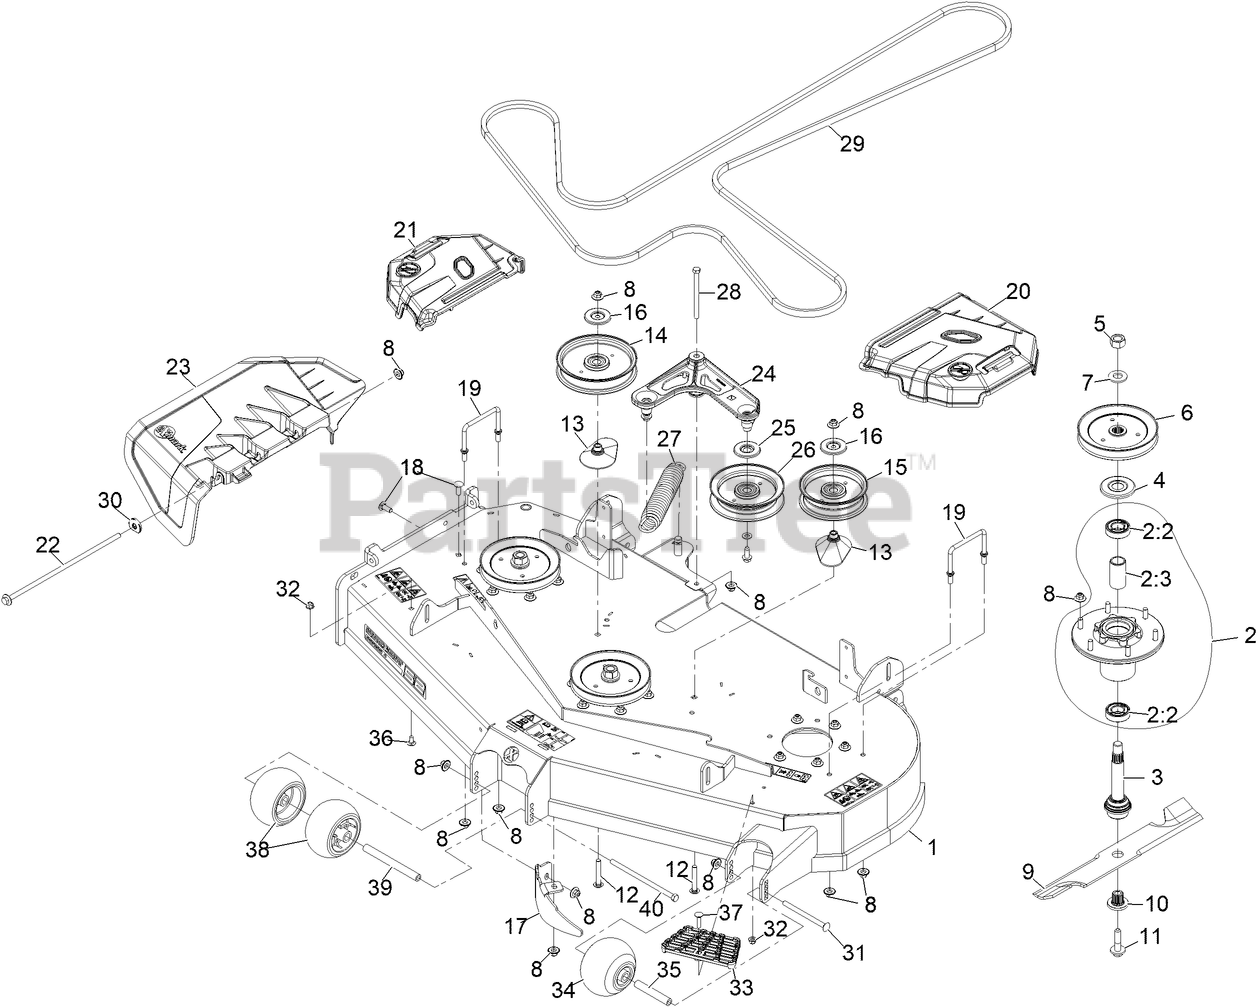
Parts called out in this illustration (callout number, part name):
1	ASM-Deck W/Decals 524
2	ASM-CUTTER HSG WITH BEARINGS
2:2	BEARING-BALL
2:3	SPACER-BEARING
3	ASM-SPINDLE AND SEAL
4	GUARD-BEARING, TOP
5	NUT-HEX
6	SHEAVE,BLADE DRIVE 6.50
8	Nut-Nyloc 3/8-16 Flg
10	BUSHING,SPLINED
11	SCREW,SEMS 1/2-20 X 2.19
12	SCREW-CARR
13	SPACER-PULLEY
14	IDLER-PULLEY, FLAT 6.00X1.00
15	IDLER-PULLEY, FLAT 5.00X1.31
16	SHIELD-DUST
17	BAFFLE-DOGLEG, LZ-VT52
18	SCREW-CARR
19	WIREFORM-COVER
20	SHIELD, LT
21	SHIELD, RT
22	Pin, Chute
23	Chute-Deck Discharge
24	ASM-IDLER ARM W/BEARINGS
25	SHIELD-GUARD, DUST
26	IDLER-PULLEY, FLAT
27	SPRING-EXTENSION
28	SCREW-HH
30	Retainer, Chute
31	BOLT-CARR
32	NUT-HF, NI
33	STEP-DECK
34	ROLLER-SCALP, ANTI
35	SPACER-AXLE
36	SCREW-CARR
37	Bolt-Carriage 5/16-18 X 1 1/4
38	ROLLER-SCALP, ANTI
39	SPACER-WHEEL
40	SCREW-HH
